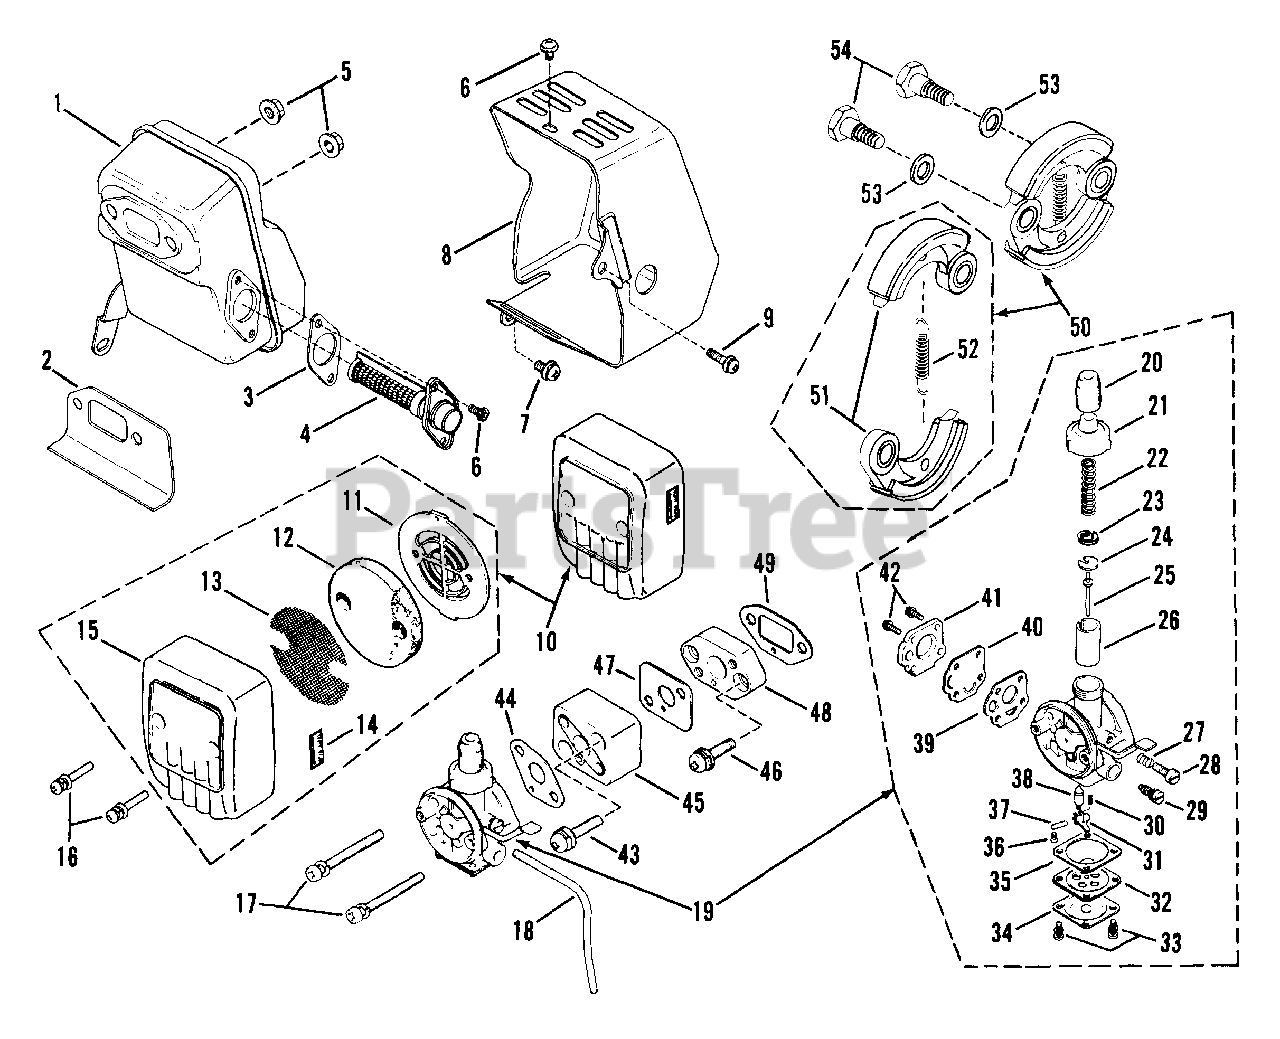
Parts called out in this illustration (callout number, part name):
1	MUFFLER
2	GASKET, Muffler
3	GASKET, Spark Arrester
4	SPARK ARRESTER
5	LOCKNUT
8	COVER, Muffler
9	SCREW
10	AIR CLEANER ASSM'Y.
11	HOLDER, Element
12	ELEMENT
13	SCREEN, Steel
14	NAMEPLATE, Choke
15	COVER, Air Cleaner
16	SCREW, Cover
17	SCREW, Carburetor
18	TUBE, Overflow
19	CARBURETOR ASSM'Y.
20	CAP, Rubber
21	CAP, Mixing Chamber
22	SPRING, Throttle
23	CLIP, Needle
24	RETAINER, Spring
25	NEEDLE, Jet Assm'y.
26	VALVE, Throttle
27	SPRING, Throttle Adj. Screw
28	SCREW, Throttle Adj.
29	NEEDLE, Main Jet Assm'y.
30	SPRING, Inlet Valve
31	ARM, Float
32	DIAPHRAGM, Main Assm'y.
34	COVER, Main Diaphragm
35	GASKET, Main Diaphragm
36	SCREW, Float Pin Set
37	PIN, Float
38	VALVE, Float
39	GASKET, Main Diaphragm
40	DIAPHRAGM, Pump
44	GASKET, Carburetor
45	FLANGE, Intake (B)
48	FLANGE, Intake (A)
49	GASKET (A)
50	CLUTCH ASSM'Y.
51	SHOE, Clutch
54	BOLT, Clutch
